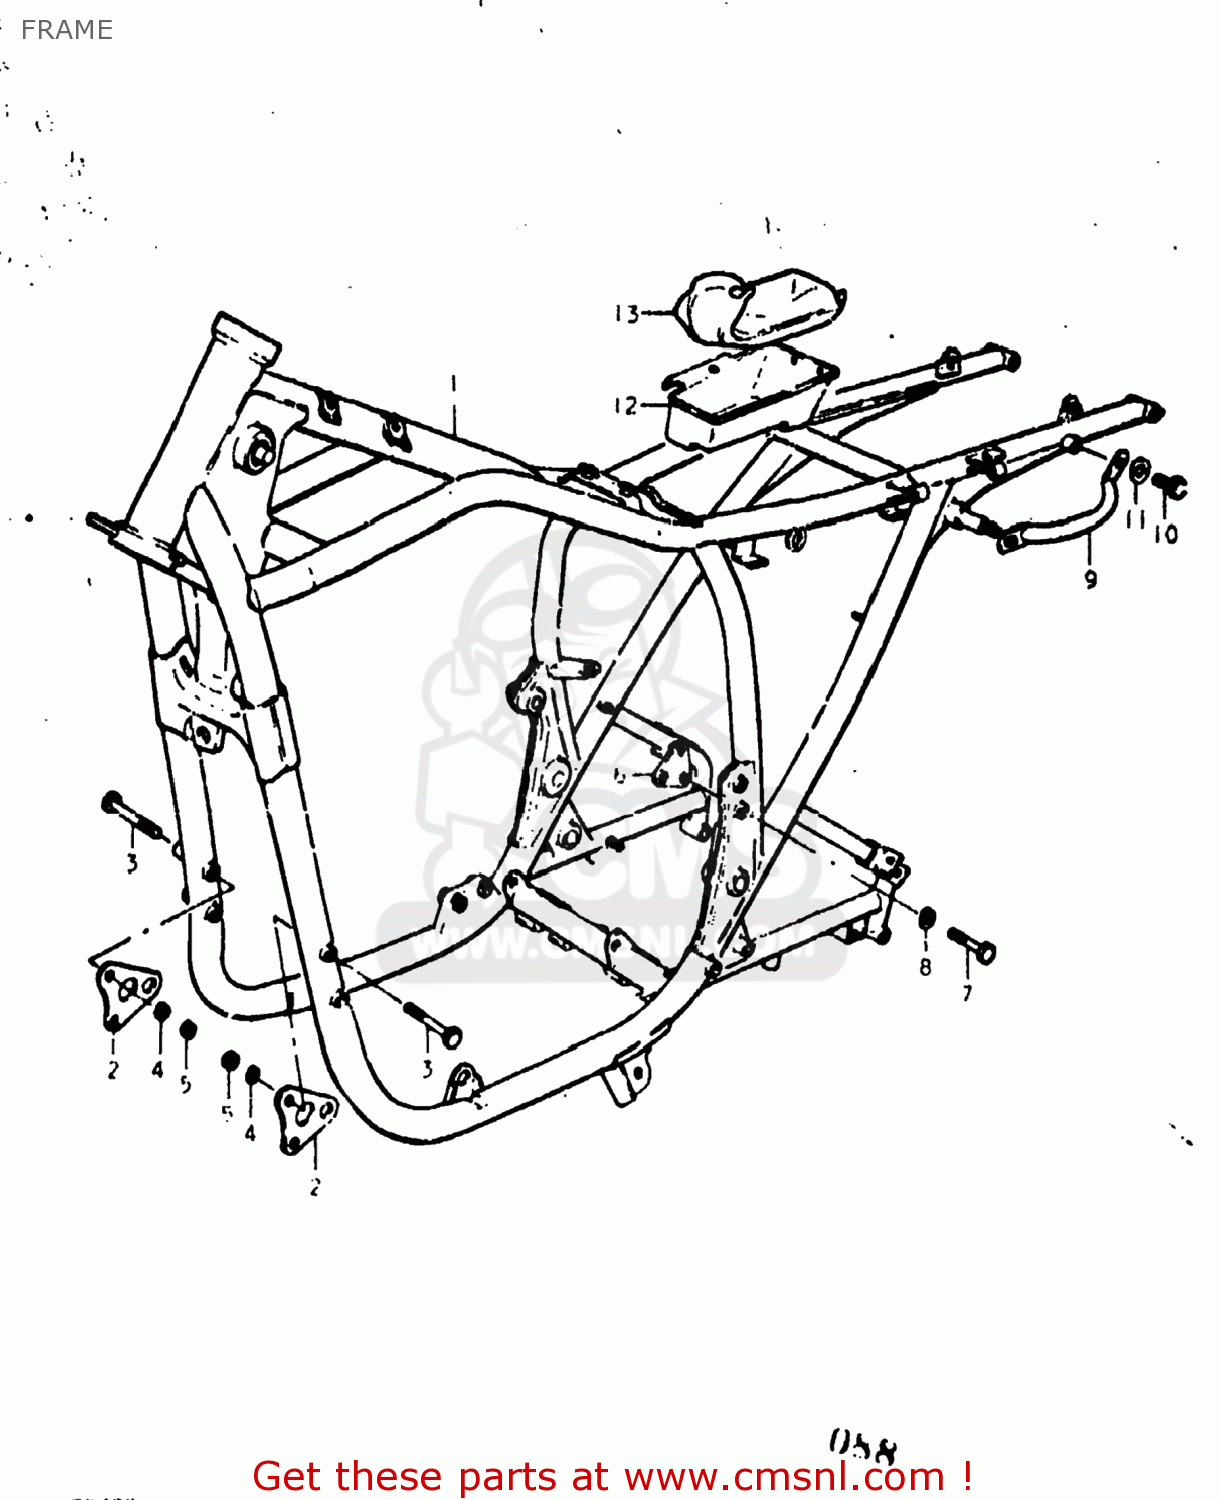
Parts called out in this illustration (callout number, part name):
1	FRAME
2	PLATE,ENGINE MOUNTING
3	BOLT
4	LOCK WASHER
5	NUT
6	PLATE,ENGINE MOUNTING
7	BOLT 8X40
8	LOCK WASHER
9	GRIP,FRAME HANDLE
10	BOLT
11	WASHER
12	HOLDER,TOOL
13	TOOL SET
